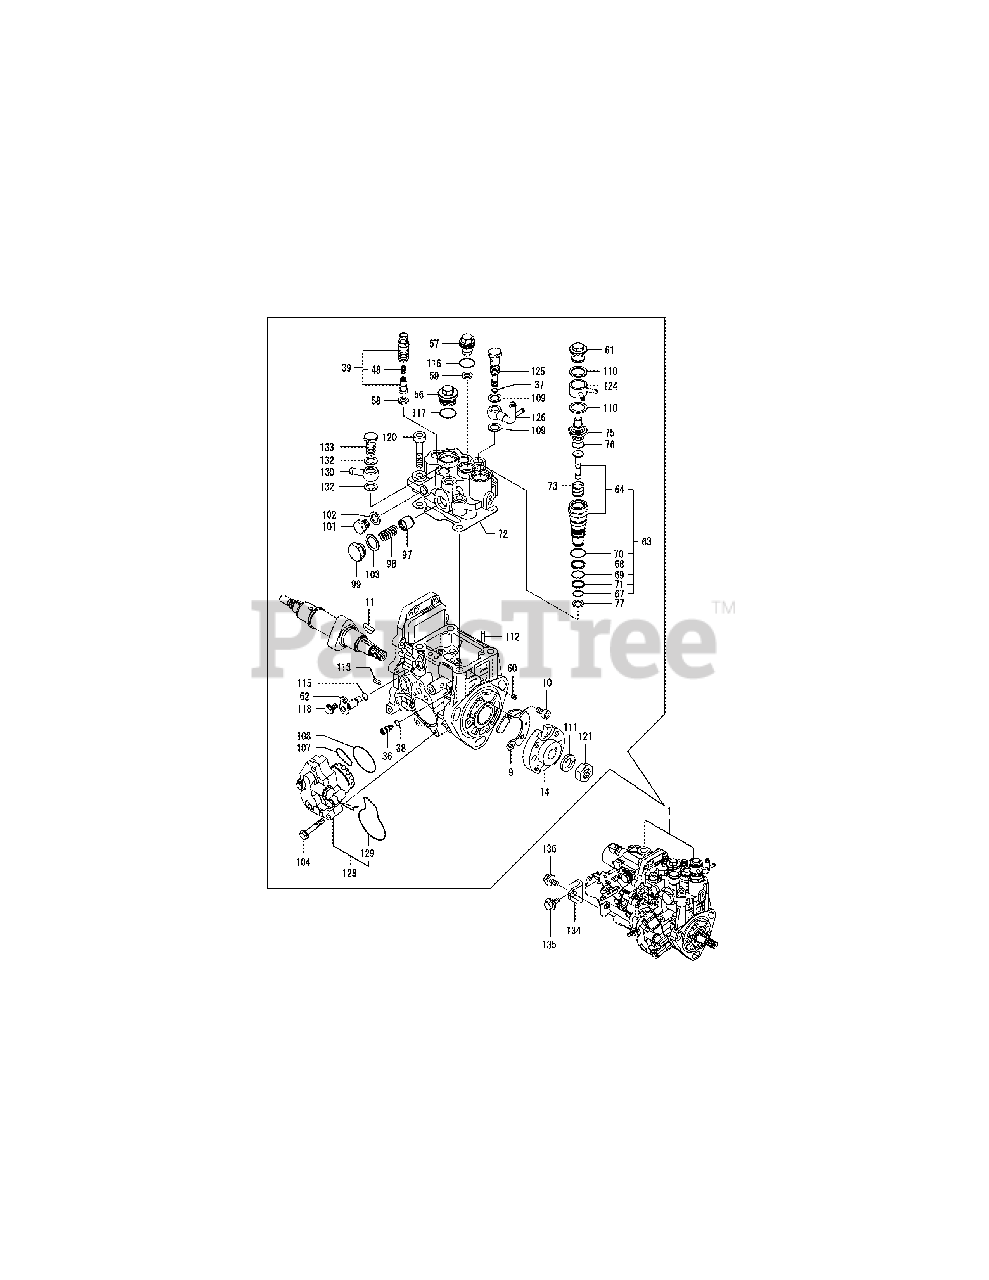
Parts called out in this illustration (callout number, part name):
1	INJECTON PUMP ASSY
11	KEY,WOODRUFF 4X16
48	SPRING,DELIVERY
58	PACKING,BARREL PLUG
59	PACKING,BARREL PLUG
61	PLUG,WATER PUMP
71	RING,BACKUP T2 P 15
75	ELEMENT, THERMO
97	PISTON,ACCUMULATOR
102	WASHER, SEAL 12
103	WASHER, SEAL 18
107	O-RING(FEED PUMP
109	WASHER, SEAL 12
110	WASHER, SEAL 18
113	PIN, 5.0A X 10
115	PACKING, P 7.0
124	JOINT,COOLING WATER
128	PUMP ASSY, FEED
129	O-RING(FEED P INNER
132	WASHER, SEAL 12
